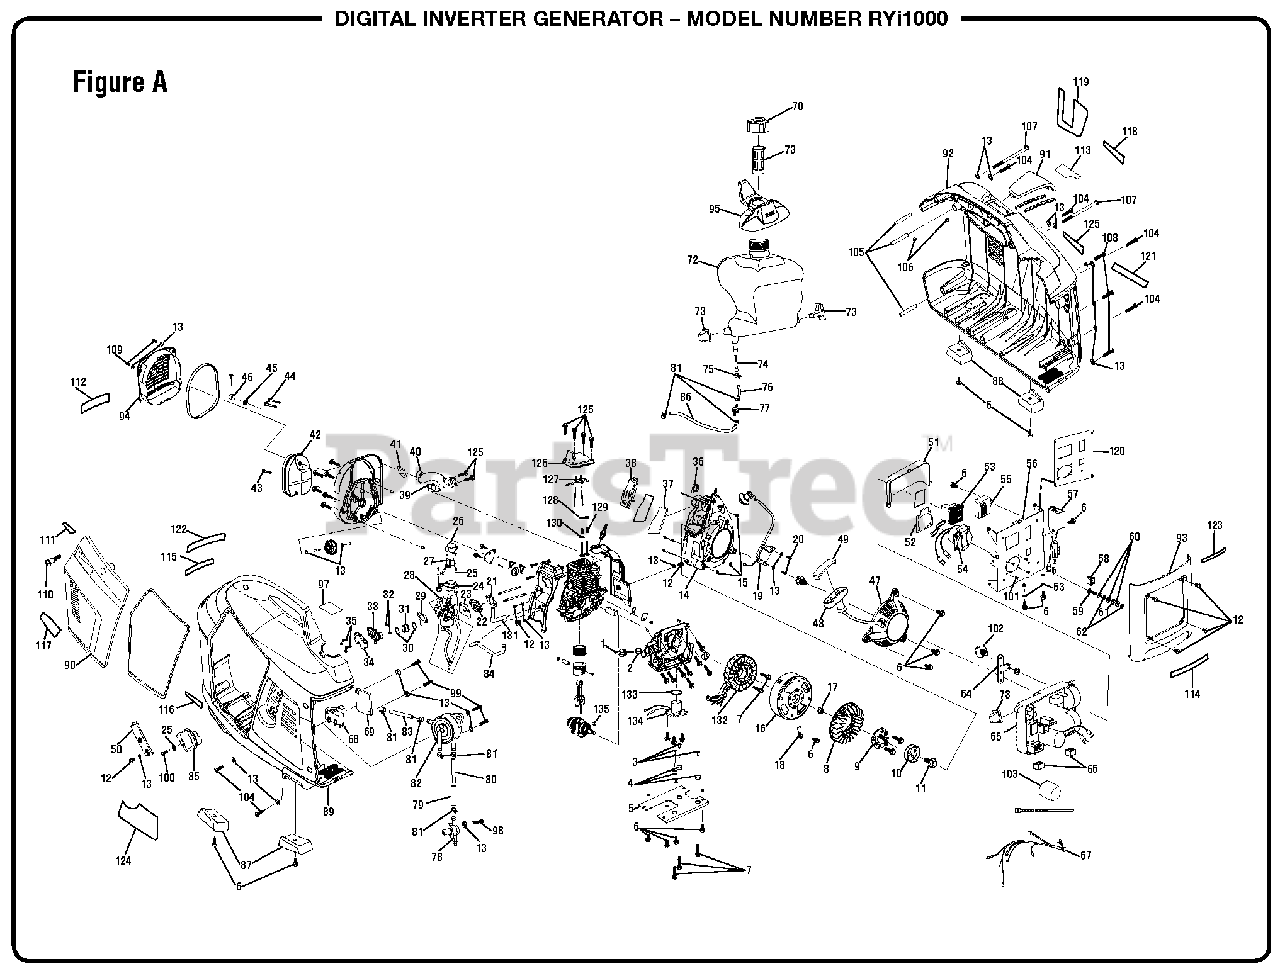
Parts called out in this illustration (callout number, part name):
2	Oil Dipstick Seal
3	Bottom Isolator Bushing
4	Bottom Isolator
5	Mounting Plate
6	Bolt (M5 x 12 mm)
7	Bolt (M6 x 25 mm)
9	Recoil Starter Cup Seat
10	Recoil Starter Driving Cup
11	Bolt (M6 x 12 mm)
12	Screw (M5 x 8 mm)
14	Engine Shroud
18	Magnet Coil Pick Up
19	Ignition Coil
20	Screw (M48 x 19 mm)
21	Insulating Gasket
22	Carburetor Seat
23	Carburetor Gasket
24	Lower Cover (Motor Governor)
25	Washer (4 mm)
26	Top Cover (Motor Governor)
27	Motor Governor
29	Intake Pipe Gasket
30	Intake Pipe Clip
31	Intake Pipe Joint
32	Intake Pipe Nest
33	PVC Intake Pipe (Lower Cover)
34	PVC Intake Pipe (Top Cover)
35	Screw (M42 x 8 mm)
36	Air Cleaner Baffle
37	Air Filter Element
38	Air Cleaner Cover
39	Exaust Pipe Gasket
40	Exhaust Pipe Outlet
41	Muffler Gasket
43	Bolt (M6 x 40 mm)
44	Bolt (M6 x 55 mm)
45	Spark Arrestor
46	Spark Arrestor Bracket
47	Starter Recoil
48	Recoil Handle
50	Handle Support
51	Electrical Panel Inner Cover
52	AC Socket Mat
54	AC Receptacle (15A)
55	Ignition Module
57	Bridge Rectifier
59	Screw (M5 x 16 mm)
60	Washer (M5)
61	Lock Washer (5 mm)
63	Star Washer (6 mm)
65	Inverter Module
66	Lower Support
67	Wiring Harness
68	Engine Switch
69	Engine Switch Cover
72	Fuel Tank
73	Fuel Tank Support
74	Inline Fuel Filter
75	Clamp (10 mm)
76	Fuel Tube (M4 x 8 mm)
77	Fuel Filter Inline (25 in)
78	Fuel Valve
79	Sleeve (8 mm)
80	Fuel Tube (M4 x 8 mm)
81	Fuel Hose Clamp (M95 x 08 mm)
82	Fuel Pump
83	Fuel Tube (M4 x 8 mm)
84	Vacuum Hose (Engine To Fuel Pump)
85	Switch Handle
86	Fuel Hose (Filter To Valve)
87	Rubber Foot (Left)
88	Rubber Foot (Right)
89	Housing Assembly w/Label (Left)
90	Maintenance Cover w/Seal
91	Spark Plug Maintenance Cover
92	Housing Assembly w/Label (Right)
93	Front Panel w/Labels
94	Muffler Cover
95	Fuel Overspill Guard
96	Danger Icon Label (Sp)
97	CPSC Label
98	Screw (M42 x 16 mm)
99	Screw (M42 x 12 mm)
100	Screw (M4 x 16 mm)
101	Screw (M4 x 8 mm)
102	Screw (M6 x 10 mm)
103	Heat Shrink Tube
104	Screw (M5 x 20 mm)
107	Screw (M5 x 100 mm)
108	Screw (M48 x 16 mm)
109	Screw (M5 X 16 mm)
110	Maintenance Cover Screw
111	Choke Label
112	Combustion Label
113	Danger/E85 Label
114	Ground Warning Label
115	Hot Surface Label
116	Lubricant Label
117	Logo Label (Right)
118	Logo Label (Left)
119	Performance Label
120	Control Panel Label
121	Data Label
122	Fire Distance Label
123	Ryobi Logo Label
124	Start Label
125	Bolt (M5 x 20 mm)
126	Cylinder Head Cover
127	Rocker Arm
128	Valve Retainer
129	Valve Spring
131	Engine Ventilation Hose
132	Stator Assembly
133	Oil Sensor Seal
134	Oil Sensor
135	Engine Shaft Key
